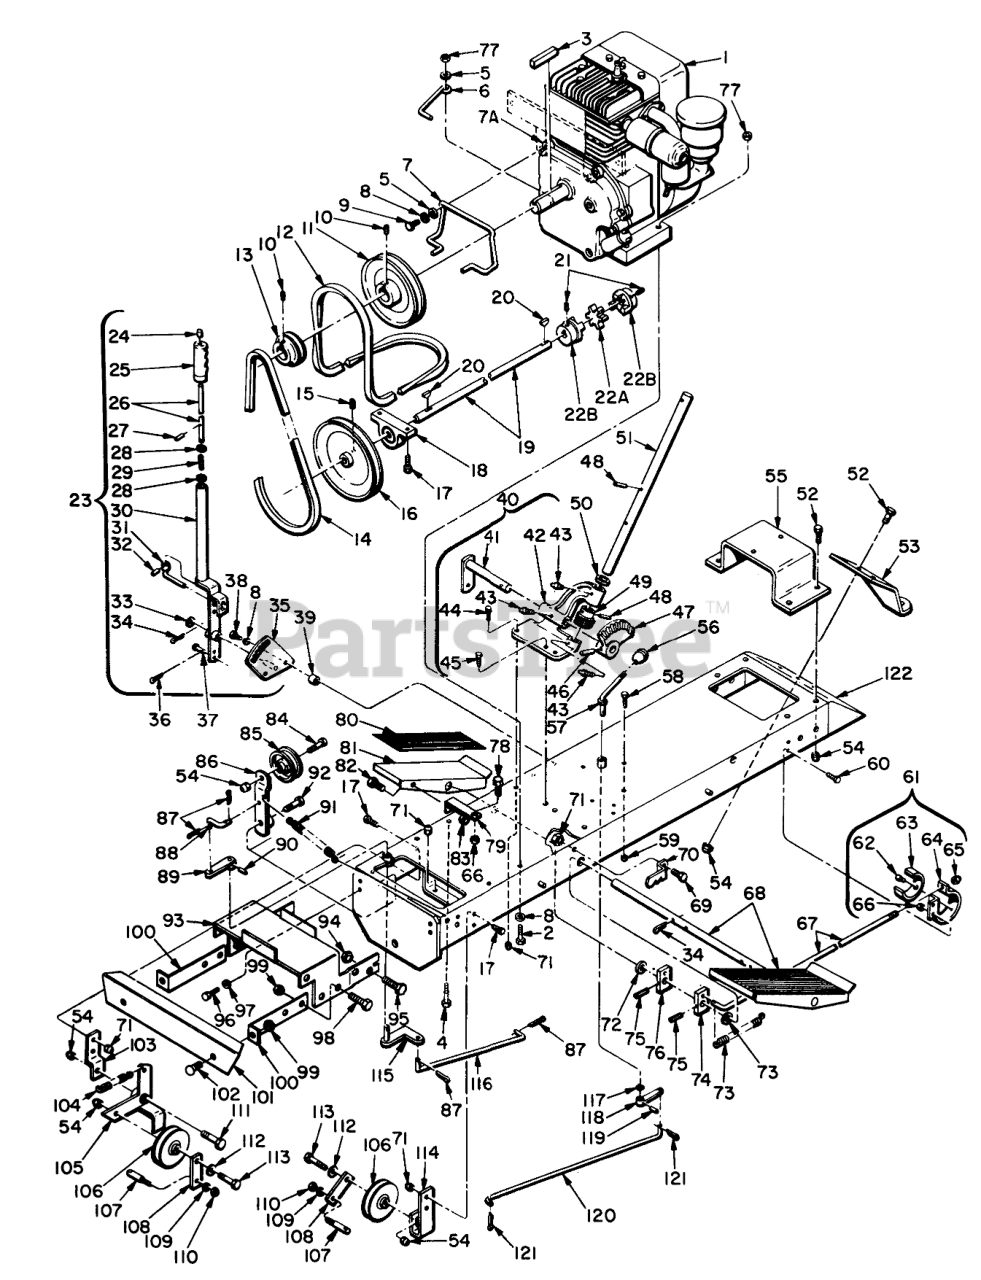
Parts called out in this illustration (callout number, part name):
1	7 HP Engine, B/S
1	Engine (Electric Start)
2	SCREW-HH
3	KEY-SQUARE
4	SCREW-HH
5	WASHER-FLAT
6	Belt Guide
7	Belt Guide
7A	Spacer
8	WASHER-LOCK
9	SCREW-HH
10	SCREW-SQH
11	Engine Pulley
13	Engine Pulley
15	SCREW-SQH
16	Pulley
17	SCREW-HH
18	Pillow Block Bearing
19	Shaft
20	KEY-WOODRUFF
21	SCREW-SET
22	Coupling (Consists of:)
22A	a. Cushion (black)
22B	b. Couplers
23	Lift Handle Assy
25	Handle Grip
26	Lift Rod
27	Roll Pin
28	Washer
29	Spring
30	Lower Handle
31	Lift Lock
32	PIN-SPRING
33	Washer
34	PIN-COTTER
35	Quadrant
36	PIN-COTTER, HAIR
37	Pin
38	SCREW-HH
39	Spacer
40	Steering Assy
41	Steering Shaft Assy
42	Steering Support
43	Grease Fitting
44	SCREW-HH
45	SCREW-HH
46	Roll Pin
47	Steering Gear
48	PIN-ROLL, SLOTTED
49	Pinion Gear
50	Washer
51	Steering Post
52	SCREW-HH
53	Hitch
54	Nut
55	Seat Bracket
57	Blade Rod Assy
58	Stud Screw
59	NUT-LOCK, NI
60	SCREW-HH
61	Brake Liner Assy
63	Brake Liner
64	Brake Band
66	Nut
67	Brake Rod
68	Clutch Pedal Assy
69	Shoulder Bolt
70	Brake Strap
72	Washer
73	Spring
74	Bracket
75	Roll Pin
76	Bracket
78	SCREW-HH
79	Foot Rest Bracket
80	Foot Pedal Pad
81	Pedal
82	SCREW-HH
83	Nut
84	SCREW-HH
85	Pulley
86	Idler Arm Assy
87	PIN-COTTER
88	Control Rod
89	Lever
91	Spring
93	Chassis Extension
94	Nut
95	SCREW-HH
96	SCREW-HH
97	WASHER-LOCK
98	SCREW-HH
100	Bumper Brace
101	Bumper
102	BOLT-CARR
103	Bracket
104	Spring
105	Idler Arm Assy
106	Idler-V
107	Belt Guide
108	Belt Guide Bracket
109	WASHER-LOCK
110	NUT-HEX
111	SHOULDER BOLT
112	WASHER-FLAT
113	SCREW-HH
114	Idler Support
115	Clutch Lever
116	Clutch Rod
117	WASHER-SPRING
118	Lever
119	Shear Proof Pin
120	Idler Rod
121	PIN-COTTER
122	Chassis Assy
